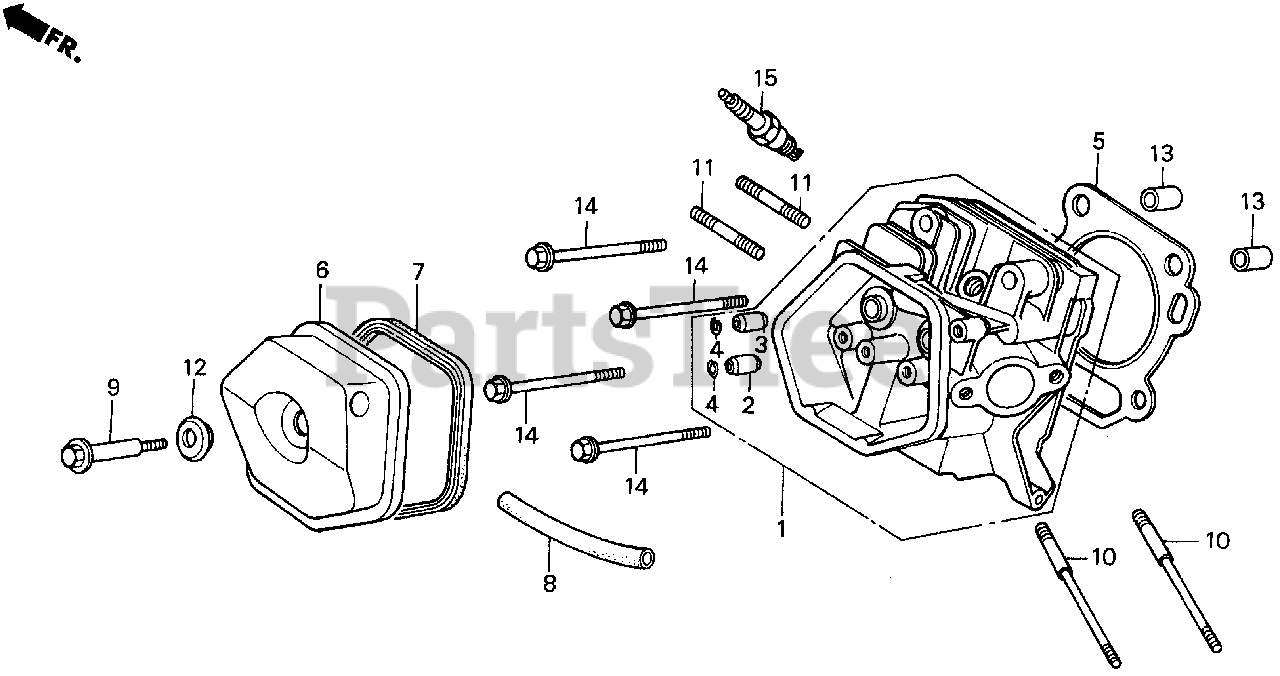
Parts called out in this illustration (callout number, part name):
1	CYLINDER HEAD
2	GUIDE, VALVE (OS)
3	GUIDE, EX. VALVE (OS)
4	CLIP, VALVE GUIDE
5	GASKET, CYLINDER HEAD
6	COVER KIT, HEAD
7	GASKET, CYLINDER HEAD COVER
8	TUBE, BREATHER
9	BOLT, HEAD COVER
10	BOLT, STUD (8X123)
11	BOLT, STUD
11	BOLT 2, STUD (8X32)
12	WASHER, HEAD COVER
13	PIN A, DOWEL (12X20)
14	BOLT, FLANGE (10X80)
15	SPARK PLUG (BPR5ES) (NGK)
15	SPARK PLUG (W16EPR-U) (DENSO)
